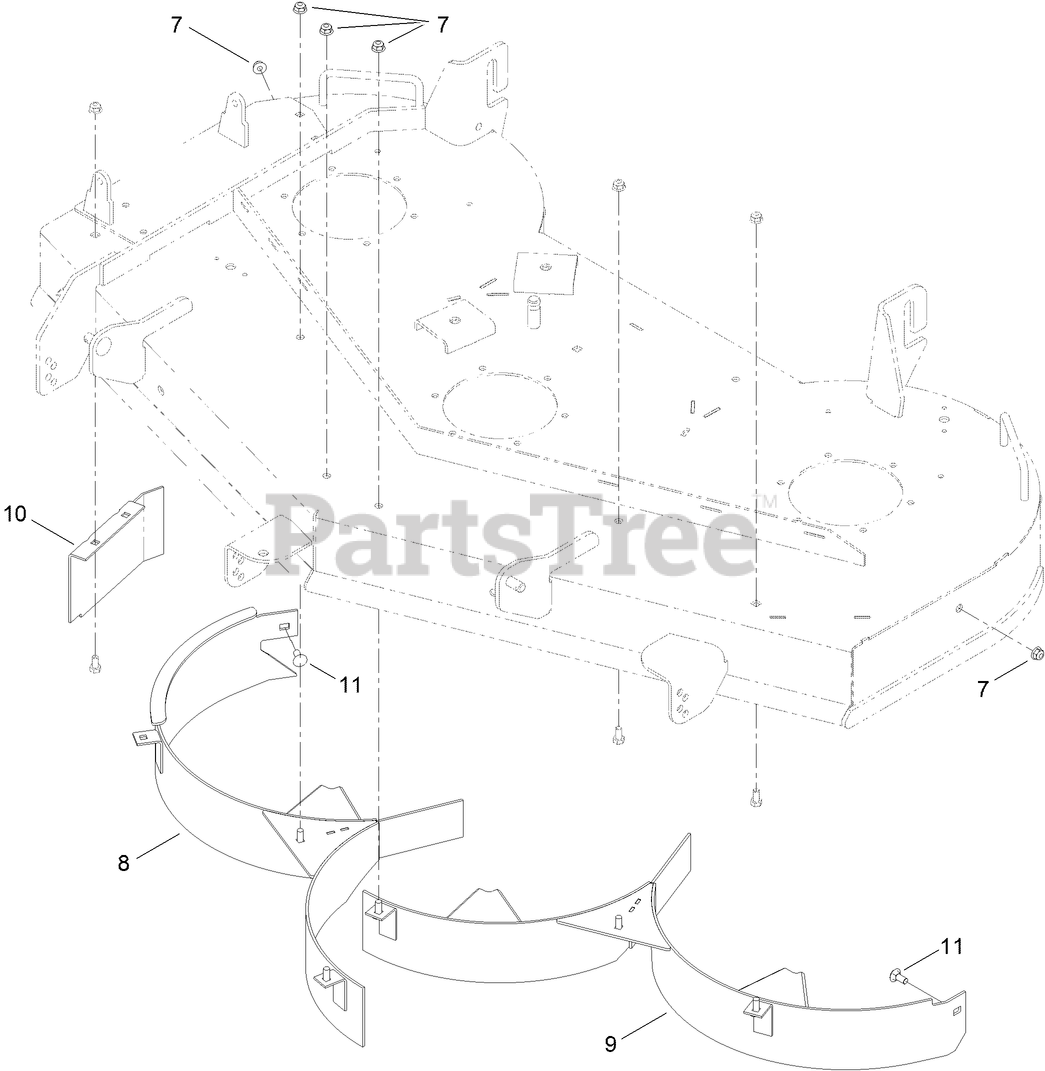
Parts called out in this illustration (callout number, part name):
7	NUT-HF, NI
8	BAFFLE-RECYCLER, RH
9	BAFFLE-RECYCLER, LH
10	GUARD-BAFFLE
11	BOLT-CARR
